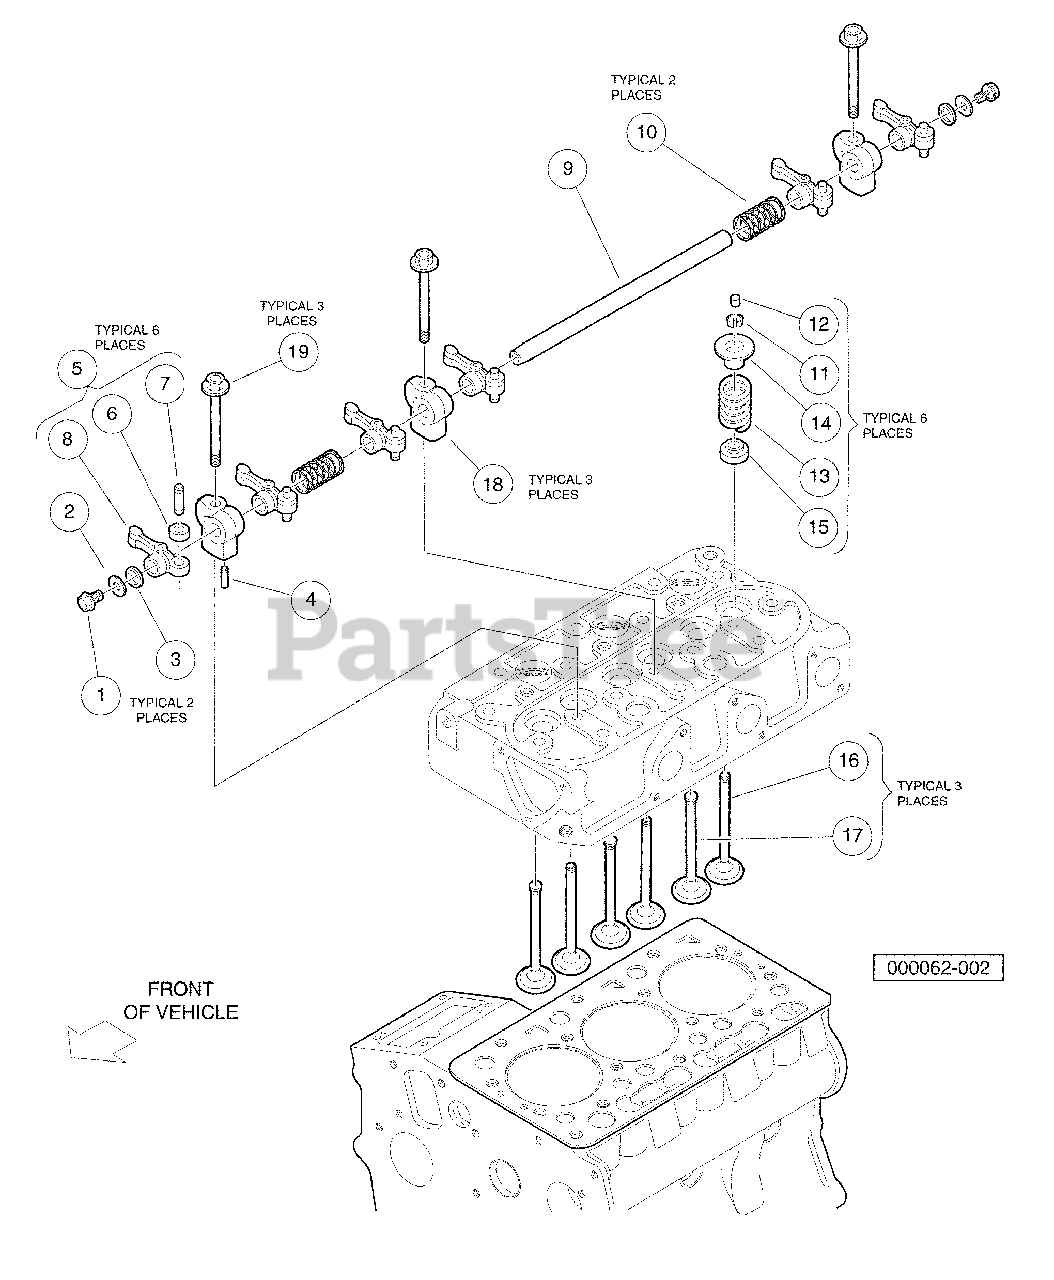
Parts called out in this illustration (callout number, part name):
1	Bolt, M6 X 1 X 8
2	Washer, D722, Plain, Rocker
3	Washer, Rocker Arm
4	Pin, Spring, D722, Rocker
5	Assy Rocker Arm
7	Screw-Adjusting
8	Arm, Rocker
9	Shaft, Rocker Arm
10	Spring, Rocker Arm
11	Collet, Valve Spring, Set
12	Cap, Valve, D722
13	Spring, Valve
14	Retainer, Spring
15	Seal, Valve Stem
16	Valve, Exhaust
17	Valve, Inlet
18	Bracket, Rocker Arm, D722 Closed-Breather
19	Bolt, Rocker Arm
